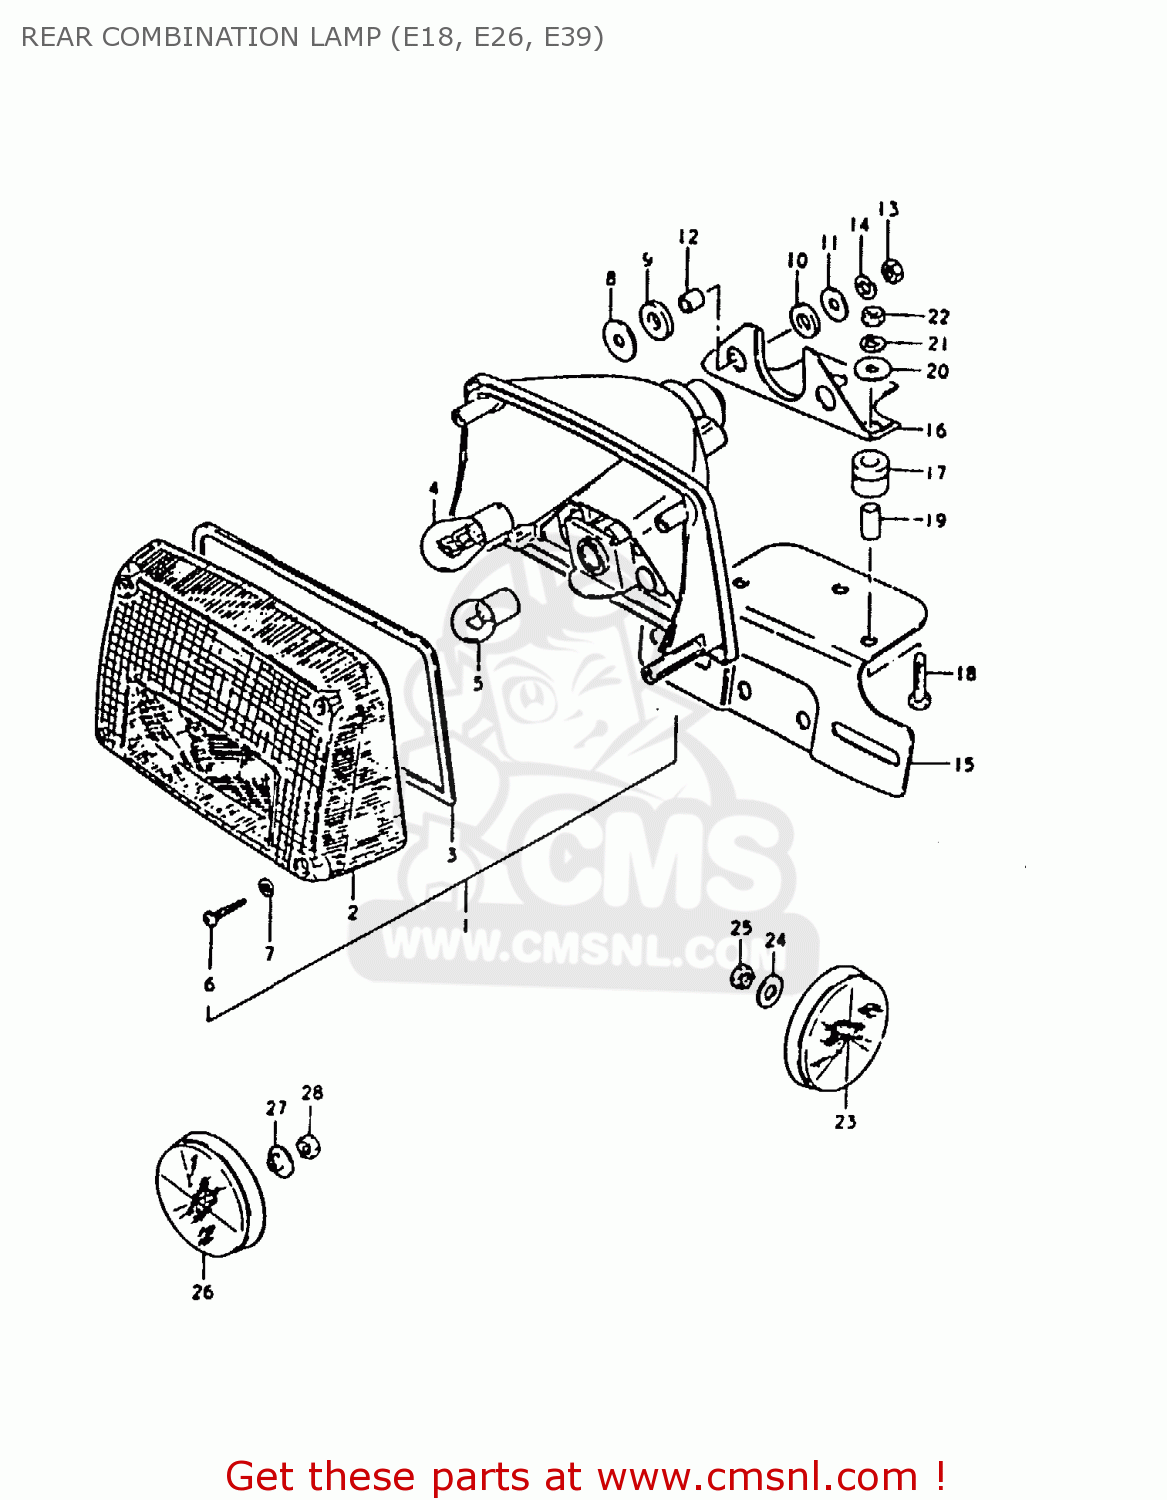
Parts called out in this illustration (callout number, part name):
1	LAMP, REAR COMBINATION
2	LENS
3	GASKET (NAS)
4	BULB 12V21/5W
5	BULB
6	SCREW
7	GASKET (NAS)
8	WASHER
9	CUSHION
10	CUSHION
11	WASHER(6,5X22X1.6)
12	SPACER(6.1X9X7.5)
13	NUT
14	LOCK WASHER
15	BRACKET, LICENCE PLATE
16	BRACKET,LICENSE PLATE
17	CUSHION, BRACKET
18	BOLT
19	SPACER (6.4X9X15.5)
20	WASHER
21	LOCK WASHER
22	NUT
23	REFLEX REFLECTOR,RR
24	WASHER
25	NUT
26	REFLECTOR,REFLEX
27	SPACER
28	NUT
